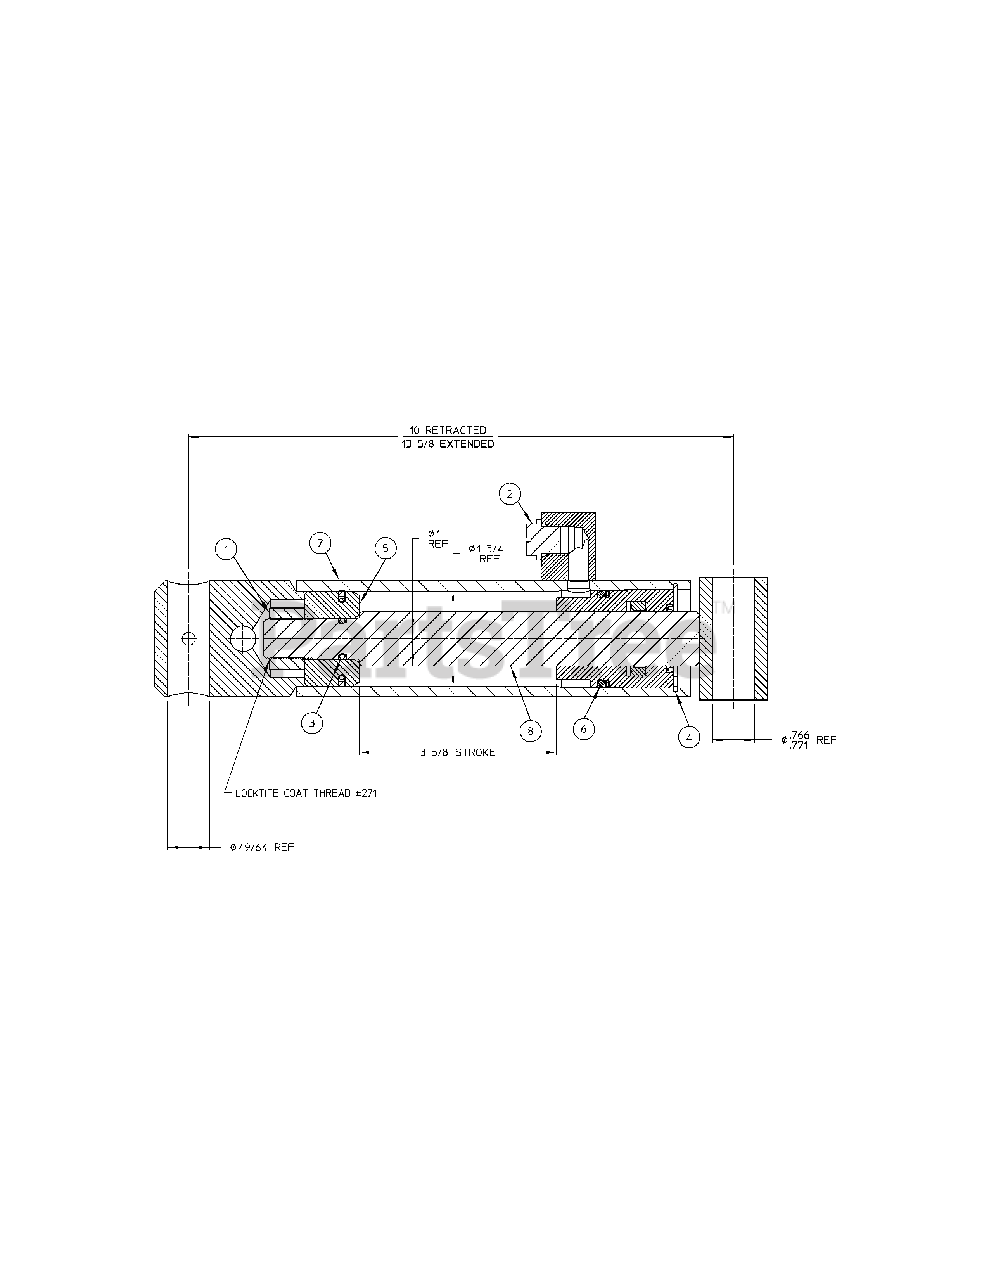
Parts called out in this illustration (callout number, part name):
1	Nut, Hex 3/4-16 GR 5 Lock
2	Cap Plug, 9/16-18 Thread with O-Ring
4	Retaining Ring
5	Piston Assembly
6	Gland Assembly
7	Cylinder Tube Weldment
8	Piston Rod Weldment
